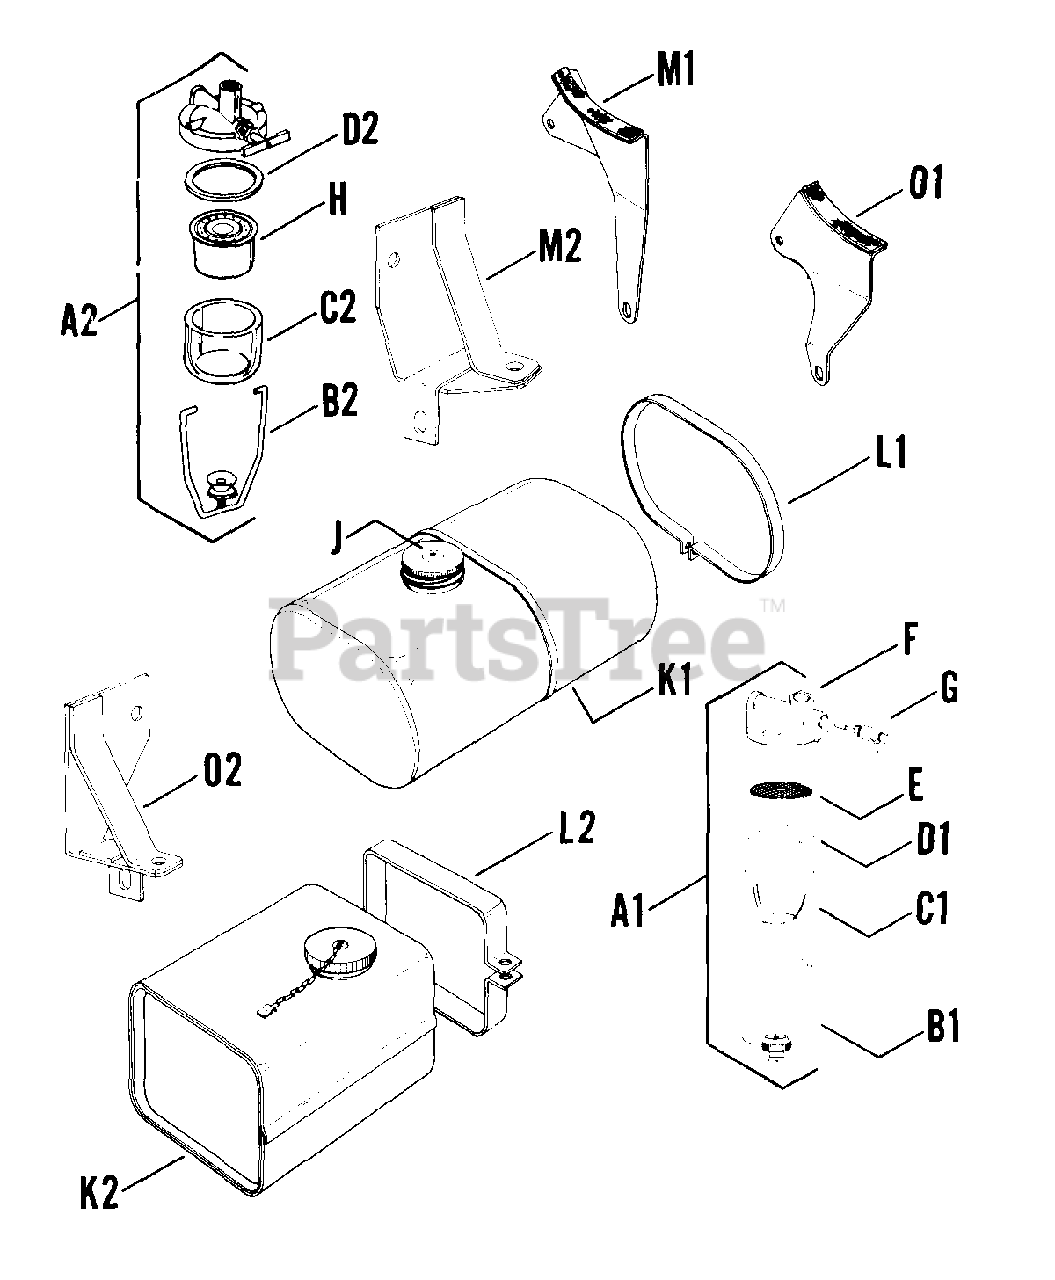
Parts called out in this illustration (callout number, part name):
A1	KIT - USE 25 755 22
B1	BAIL - DISCONTINUED
C1	BOWL
D1	GASKET
E	SCREEN
F	TOP
G	VALVE
J	CAP USE 236655-S
K1	TANK - DISCONTINUED
M1	BRACKET - USE A-221254
O1	BRACKET - USE A-221254
